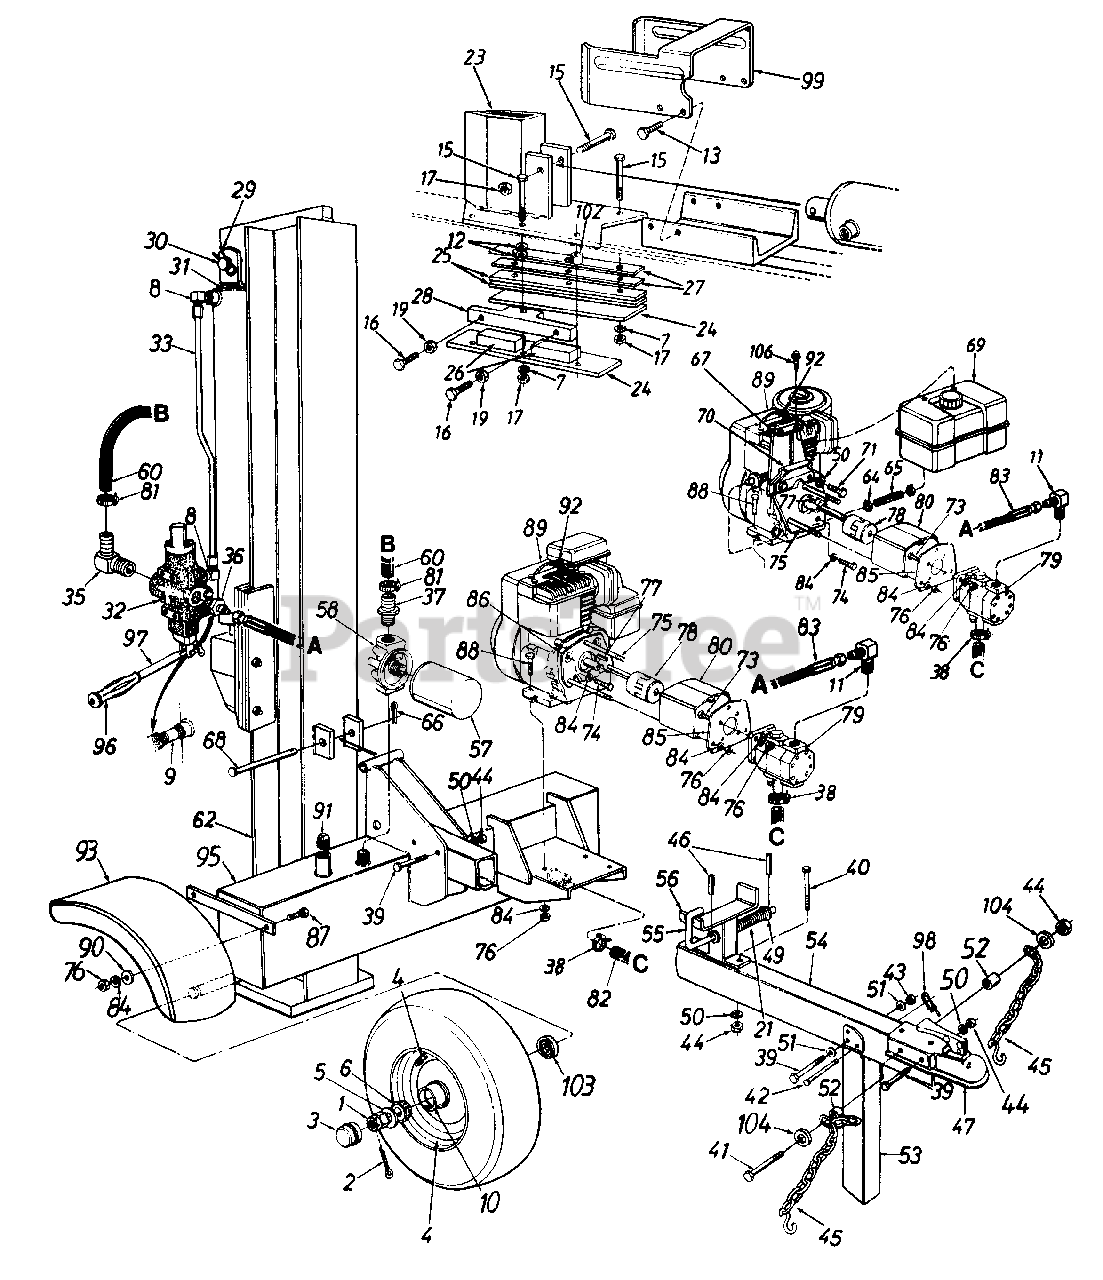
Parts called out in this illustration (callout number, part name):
1	Slotted Nut 3/4-16 Thd.
2	Cotter pin 5/32" Dia.
3	Hub Cap
5	Fl-Wash. .76" I.D. x 1.5" O.D.
6	Bearing Cone
7	L-Wash. 1/2" I.D.
8	90ø Solid Male Adaptor
9	Pipe Nipple 1/2 NPT
10	Bearing Cup
11	90ø Male Adapter
12	Fl-Wash. .531" I.D. x .94" O.D.
13	Hex Cap Scr. 3/8-16 x 1" Lg.
15	Hex Bolt 1/2-20 x 2.75" Lg. (Grade 8)
16	Hex bolt 3/8-24 x 1.5" Lg.
17	Hex L-Nut 1/2-20 Thd.
19	Hex Jam Nut 3/8-24 Thd. (Grade 5)
21	Comp. Spring 4" Lg.
29	External Cotter Pin
30	Cylinder Mounting Pin
33	Metal Pressure Tube
35	Return Elbow
36	Adapter
37	3/4" Hose Barb.
38	Hose Clamp
39	Hex Bolt 3/8-16 x 3" Lg. (Grade 8)
40	Hex Bolt 3/8-16 x 4" Lg.
41	Hex Bolt 3/8-16 x 4.25" Lg. (Grade 5)
42	Clevis Pin 5/16 x 2.5" Lg.
43	Hex L-Nut 3/8-16 Thd.
44	Hex Nut 3/8-16 Thd.
45	Chain - Tow Hitch
46	Roll Pin
47	Hitch Coupler
49	Fl-Wash. .635" I.D. x .93" O.D.
50	L-Wash. 3/8" I.D.
51	Fl-Wash. .406" I.D. x . 75" O.D.
52	Spacer .44" Lg.
55	Locking Rod
57	Filter Element
58	Filter Head
60	Return Hose 3/4" I.D. x 44" Lg.
65	Fuel Line 15" Lg.
66	Cotter Pin 1/8" Dia.
67	Tank Mtg. Brkt.
68	Hinge Pin 1/2 x 4.8" Lg.
69	Fuel Tank Ass'y.
70	Support Brkt.
71	Hex Bolt 3/8-16 x 1" Lg.
73	Hex Bolt 5/16-24 x 1" Lg.
74	Hex Bolt 5/16-24 x .62" Lg.
75	Hex Bolt 5/16-24 x 4" Lg.
76	Hex Nut 5/16-24 Thd.
77	Sq. Key 3/16" x .75"
78	Flexible Coupling
79	Gear Pump
80	Coupling Shield
81	Hose Clamp 5/8"
82	Suction Hose
83	High Pressure Hydraulic Hose 48"
84	L-Wash. 5/16" I.D.
87	Hex Bolt 5/16-24 x .75" Lg.
88	Hex Bolt 5/16-24 x 1.75" Lg.
89	Engine
90	Fl-Wash. .344" I.D. x .875" O.D.
91	L-Vent Pipe Plug
92	Spark Plug Boot
97	Control Handle
98	Spring Pin
102	Spacer 1/2" I.D. x .86" Lg.
103	Bearing Seal Only
104	Fl-Wash. 3/8" I.D. x .87" O.D.
106	Hex AB-Tap Scr. 1/4 x .75" Lg.
